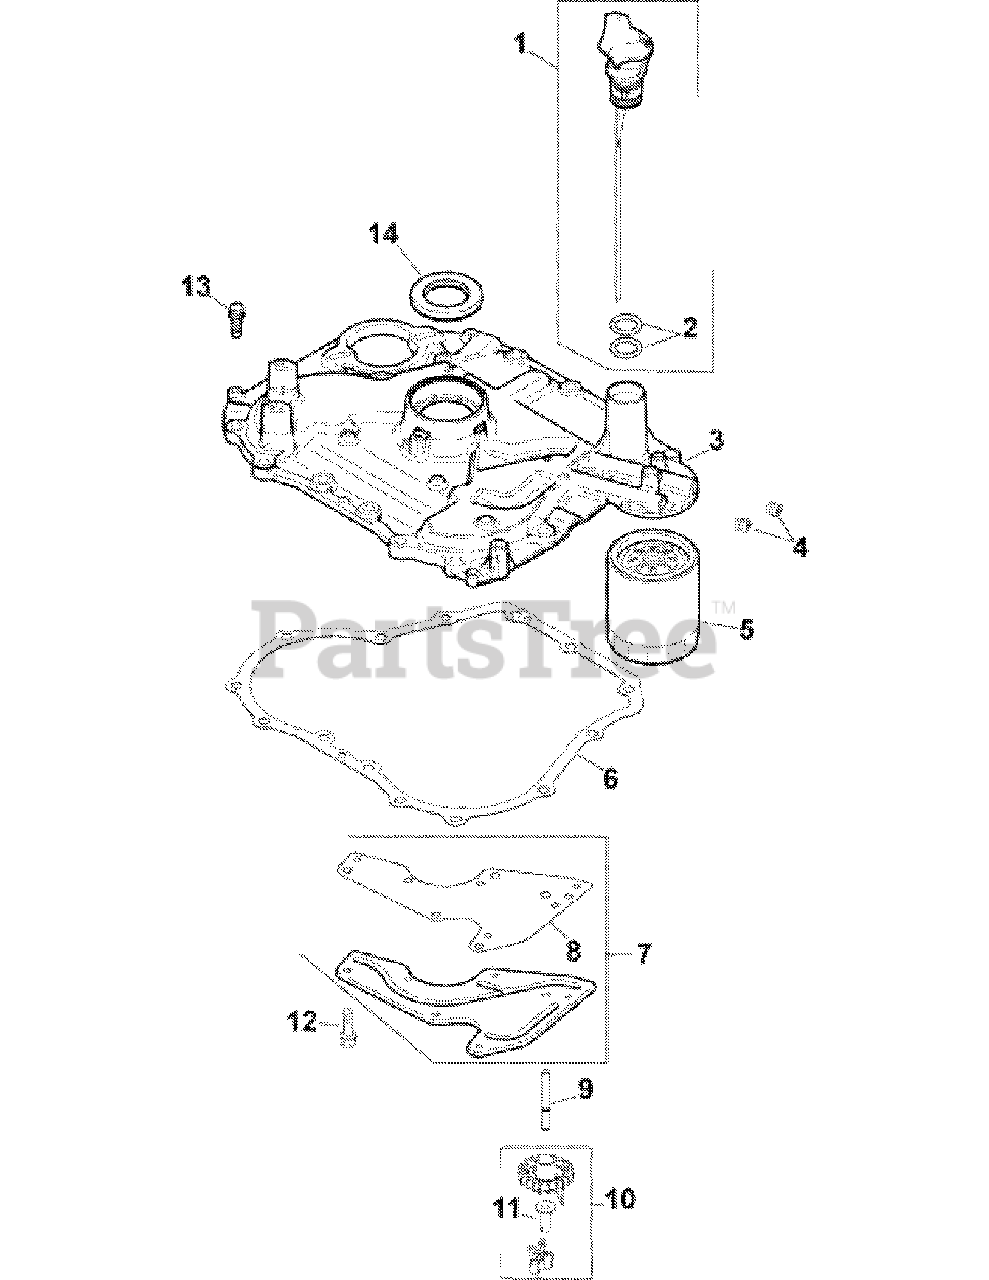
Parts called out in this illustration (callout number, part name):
1	DIPSTICK W/2 O-RINGS
2	O-RING
3	KIT PLATE ASM-CLOSUER
4	PLUG, CTSK PIPE 1/8"
6	GASKET, CLOSURE PLATE
7	KIT, OIL PASSAGE COVER
8	GASKET, OIL PASSAGE
9	SHAFT, GOVERNOR CROSS
10	KIT GEAR ASM-GOVERNOR
11	PIN, GOVERNOR REGULATING
12	SCREW, FLG THD FRM M5X0.8X13
13	SCREW, FLG M8X1.25X30
14	SEAL, OIL
